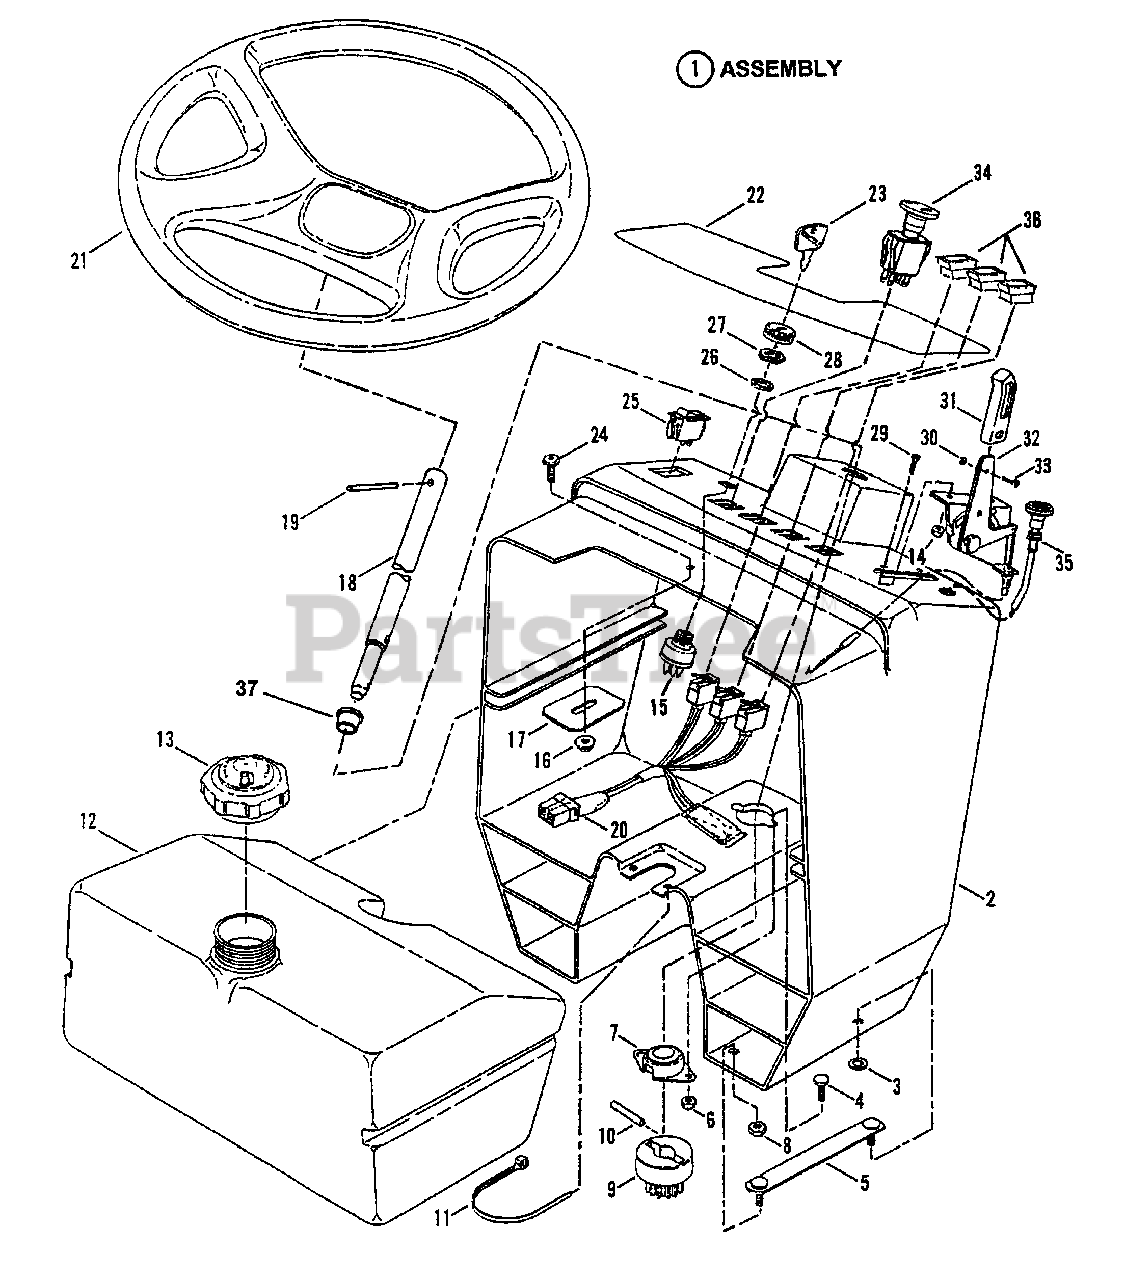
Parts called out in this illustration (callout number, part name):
1	ASSEMBLY, Console
2	CONSOLE
3	RETAINER, 5/16 Bolt
4	SCREW, 1/4-20 x 3/4" Hex Head Cap, Grade 5
5	ASSEMBLY, Strap-Clinch Stud
6	NUT, 1/4-20 Hex Nyloc
7	ASSEMBLY, Flange Bearing
8	NUT, 5/16-18 Hex Center Lock, Grade B or 5
9	GEAR, Pinion, Steering Shaft
10	PIN, Dowel, 1/4 x 1-1/4"
11	TIE, Wire
12	ASSEMBLY, Fuel Tank
13	CAP, Fuel Tank
14	NUT, #10-24 Hex Nyloc
15	KEY SWITCH
16	NUT, 5/16-18 Hex Flange Lock
17	BRACKET, Hood Latch Catch
18	SHAFT, Steering
19	ROLL-PIN, 1/4 x 2-1/4"
20	LIGHTS, Indicator
21	STEERING WHEEL
22	DECAL, Console
23	KEY, Switch (With Cover)
24	SCREW, 5/16-18 x 5/8" Truss Head, Torx
25	SWITCH, Lights
26	SPACER
27	NUT, 5/8-32 Hex
28	BEZEL
29	SCREW, #10-24 x 5/8" Machine
30	NUT, #8-32 Hex, Grade 2 or B
31	HANDLE, Throttle Control
32	CONTROL, Throttle 44.6" Long
32	CONTROL, Throttle 26.25" Long
33	SCREW, #8-32 x 3/8" Cross-Recessed, Fillester Head, Grade 2
34	SWITCH, PTO
35	CABLE, Choke 29.1" Long
36	LENS, Indicator Light
37	BEARING, 3/4" I.D.
